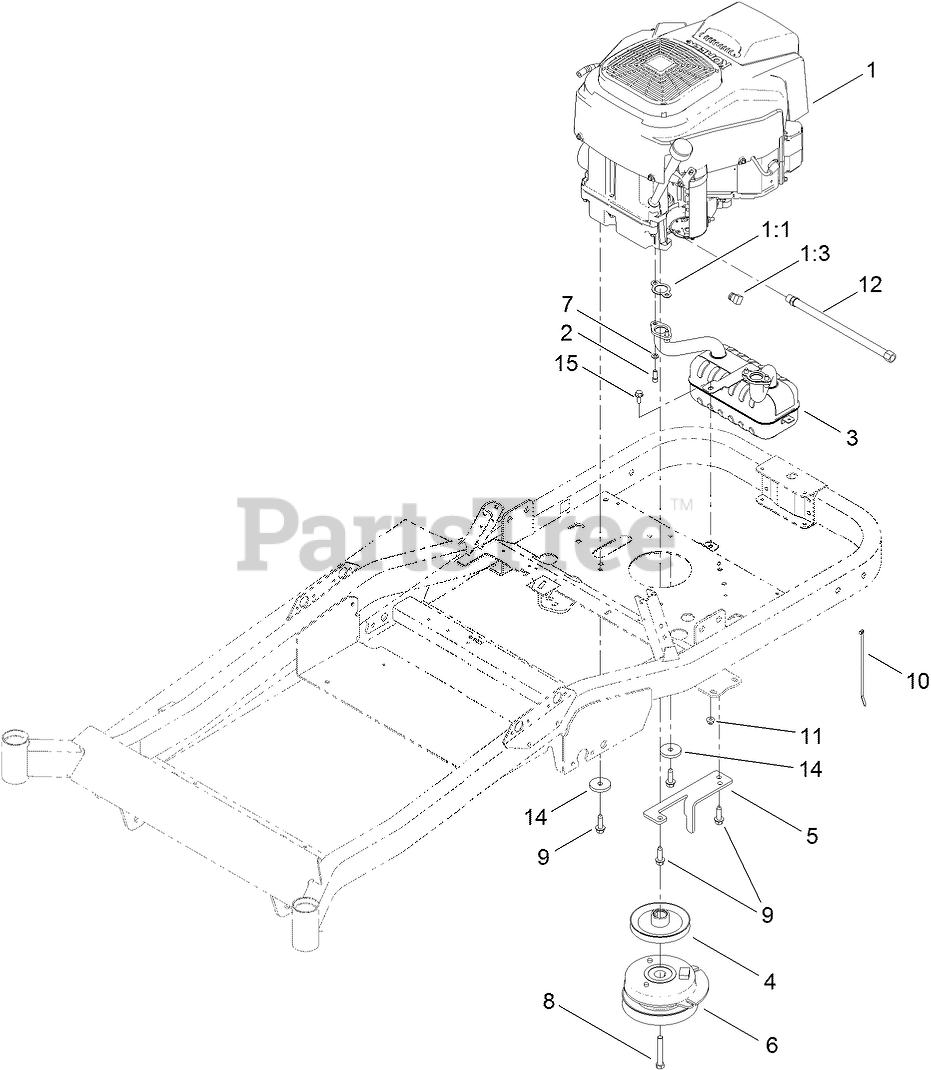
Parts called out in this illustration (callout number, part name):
1:1	GASKET-EXHAUST
1:3	PLUG-PIPE, SQH
2	SCREW-HSH
3	MUFFLER-TWIN, KOHLER
4	PULLEY-ENGINE
5	BRACKET-STOP, PTO
6	CLUTCH-ELECTRIC, PTO
7	WASHER-LOCK
8	SCREW-HH
9	SCREW-TAPTITE
10	TIE-CABLE
11	NUT-HF, NI
12	HOSE-DRAIN, OIL
14	WASHER-PLAIN
15	SCREW-HHF
